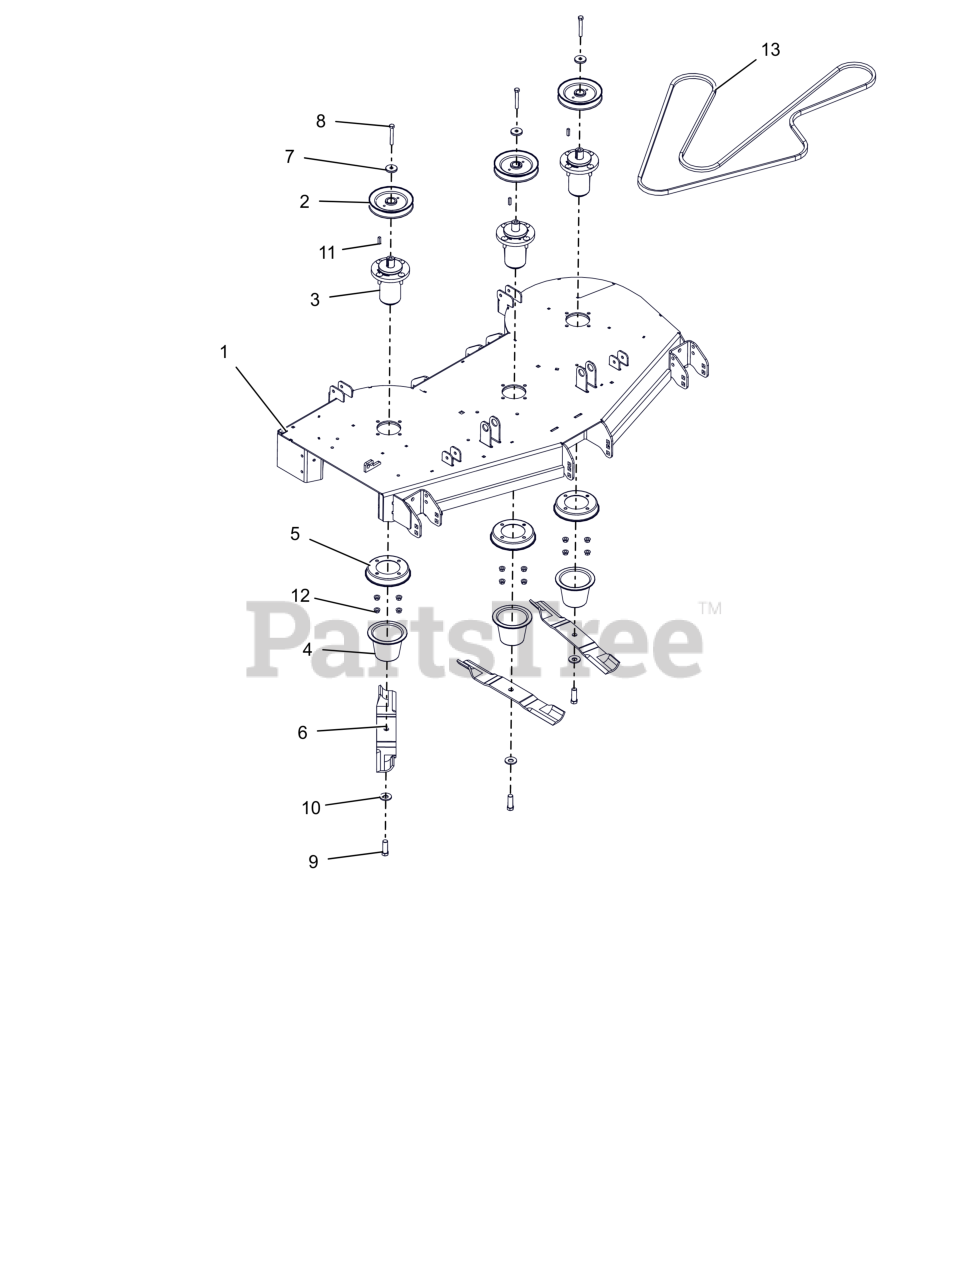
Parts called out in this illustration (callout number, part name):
1	WLDMT, 52" PRO-STANCE DECK (RED)
2	PULLEY, V-1.00 ID X 5.75 OD (BLACK)
3	ASM, MAINT FREE ALUM SPINDLE
4	GUARD, SPINDLE LOWER
5	GUARD, SPINDLE TOP
6	BLADE, 18.00" MOWER (HI-LIFT)
7	RETAINER, SHEAVE
8	BLT, HEX .38-16X2.75 G8 ZCC
9	BLT, HEX .62-18X1.75 G8 ZCC
10	WSHR-BLVL .669X1.535X.138
11	KEY, SQ .25X.25X1.00 RC 40-50
12	NUT-LK-CTR-FLG .375-16 GF ZCC
13	V-BELT, B RAW EDGE EPDM
